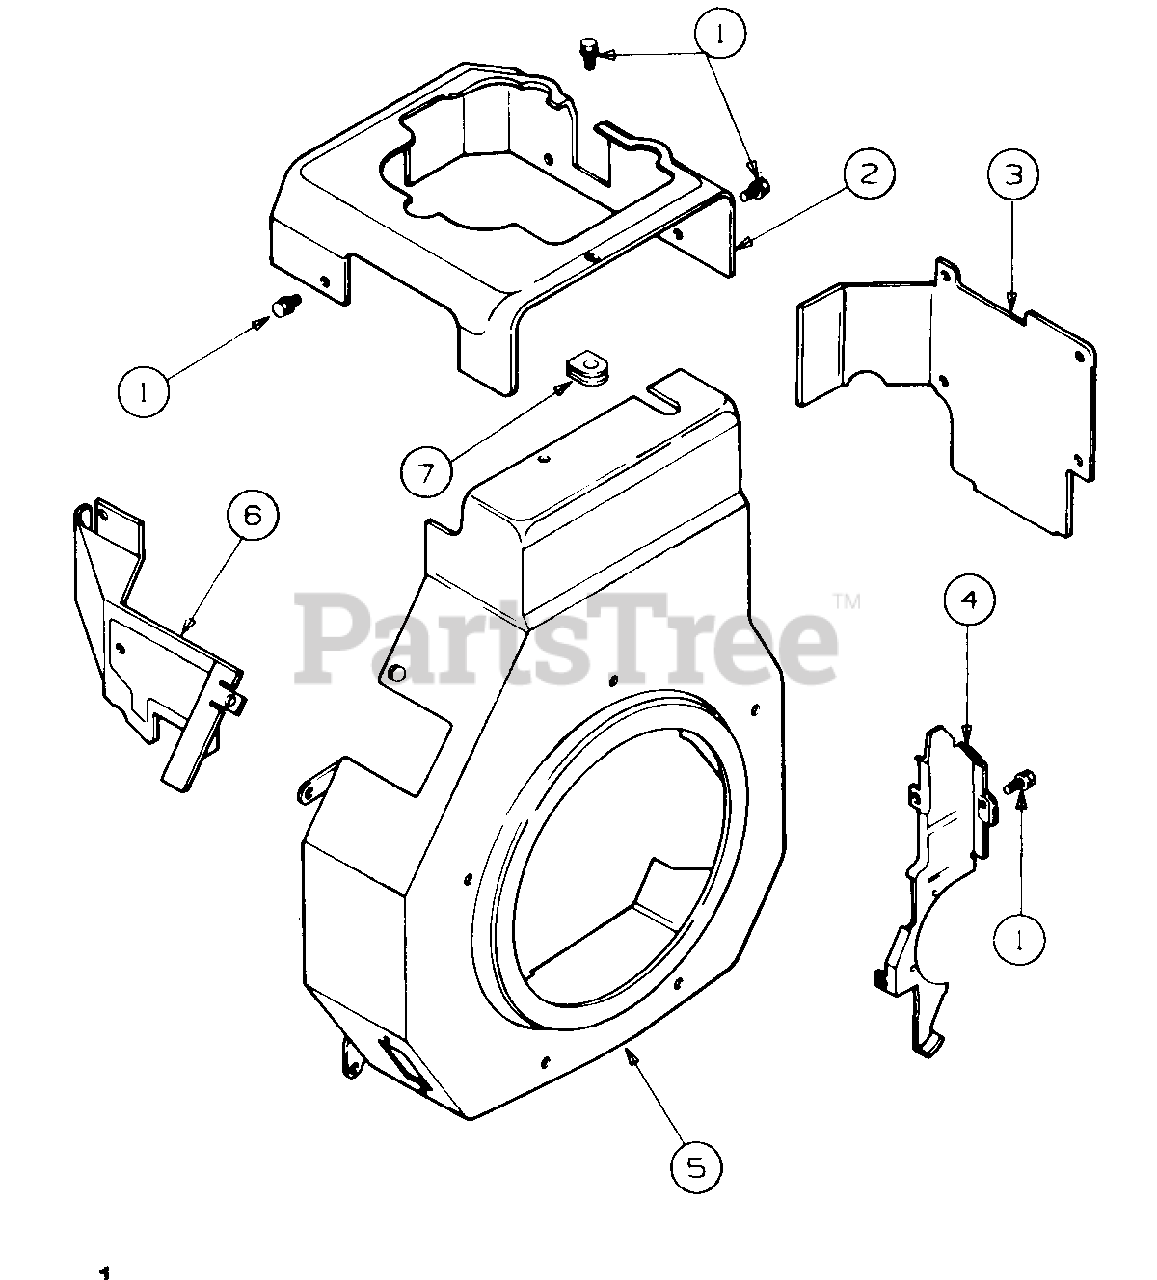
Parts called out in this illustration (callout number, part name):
1	Screw, Mounting, M5 x 0.8 x 10
2	Baffle, Cylinder Head
3	Baffle, Cylinder
4	Plate, Blower Housing
5	Housing, Blower
6	Baffle, Carburetor
7	Grommet, Blower Housing
